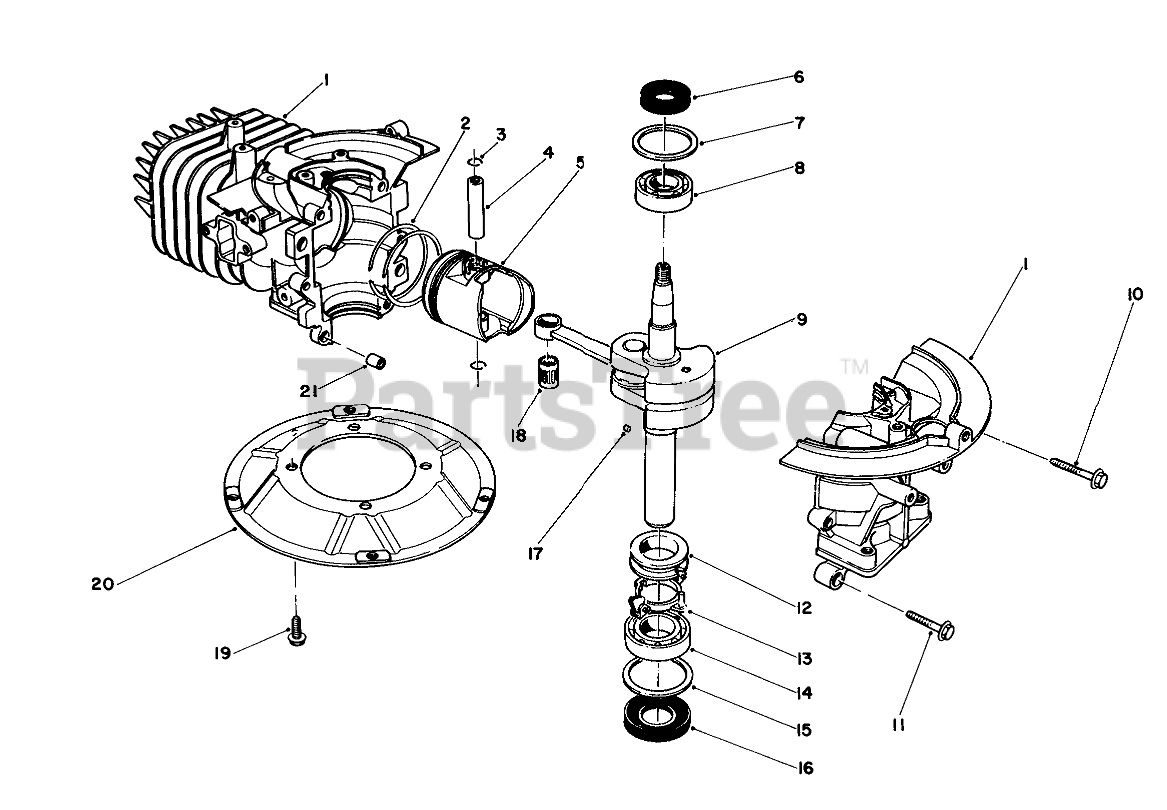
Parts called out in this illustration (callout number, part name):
1	Crankcase Assembly
2	RING SET
4	PIN-PISTON
5	Piston
6	OIL SEAL
7	WASHER-UPPER
8	BEARING-UPPER
9	CRANKSHAFT ASM
12	SPACER
13	BRACKET
14	LOWER BRG
15	WASHER-LOWER
16	SEAL-OIL
18	BEARING
20	PLATE-MOUNTING
